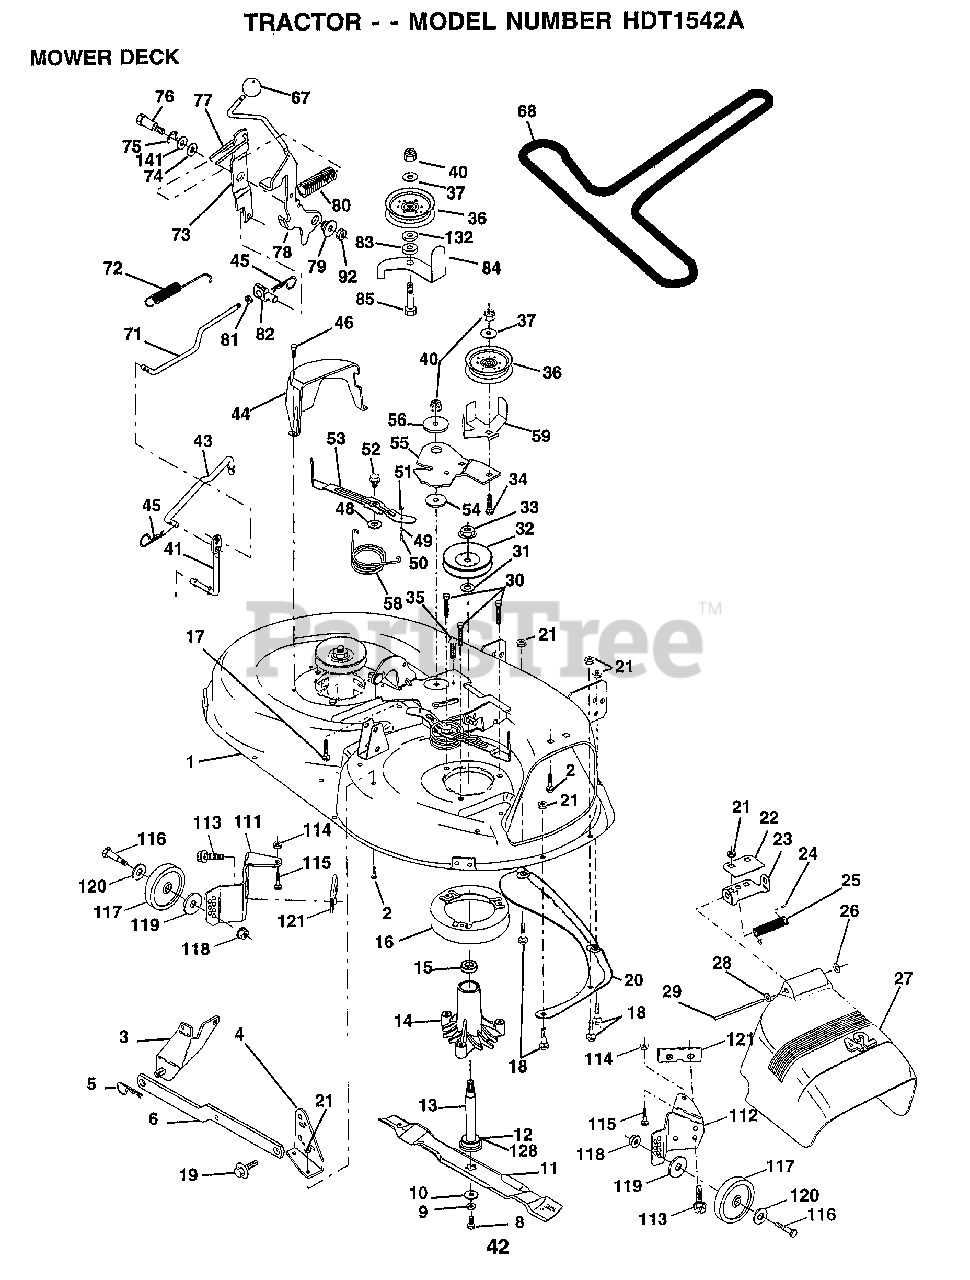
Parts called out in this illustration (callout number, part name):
1	"HOUSING ASSY.42"""
2	BOLT
3	BRKT ASM SWAY BAR
4	BRKT DECK SW BAR
8	BLADE BOLT
10	WASHER.HARD.BLADE
11	"BLADE.42"" HIPERF"
12	BEARING.BALL
14	HSG ASM MANDREL
15	BEARING
16	STRIPPER RND MWR
17	BOLT RDHD 3/8-16
18	BOLT
19	BOLT SHD 5/16-18
20	BAFFLE VORTEX 42
22	STIFFENER BRKT
23	DEFLECTOR BRKT
24	CAP-SLEEVE LT
25	SPRING TORSION
26	NUT PUSH M
27	DEFLECTOR.SHIELD
28	WASHER
29	HINGE ROD
30	"SCREW-THD ROLL,WA"
31	WASHER
32	PULLEY.MANDREL.42
34	BOLT
35	XMAS TREE FASTNER
36	FLAT IDLER PULLEY
37	WASHER
41	PIVOT ROD
43	ROD CLUTCH W/NIBS
44	GUARD MAND LH BLK
45	RETAINER M
46	SCREW.1/4-20X5/8
48	HARD SMALL WASHER
49	ROLLER ASM-CAM
50	SHOULDER BOLT
51	LOCKNUT
52	BOLT.SHLD.5/16-18
53	BRAKE PAD ARM ASM
54	HARDENED WASHER
55	ARM-IDLER
56	SPACER RETAINER
58	SPRING TORSN BRAK
59	GUARD IDLER TUV
67	KNOB.RD.7/16-14
68	BELT.V.T-PATH
71	ROD CLUTCH 38/42
72	RETURN SPRING
73	CLUTCH ARM SECOND
74	WASHER
75	RING
76	SHOULDER BOLT
77	SPRING KEEPER
78	LEVER.ASM.CLUTCH
79	BUSHING
80	SPRING.CLUTCH.MWR
81	NUT
82	TRUNION ADJ
83	WASHER
84	"KEEPER-BELT,FIXED"
85	BOLT
92	NUT
111	BRACKET.GWHL.LH.
112	BRACKET.GWHL.RH.
113	SCREW
116	BOLT M
117	WHEEL.GAGE.BLK.PL
118	LOCKNUT
119	WASHER
120	WASHER
121	BRACKET.EXTRD.GWL
128	WASHER.FELT.
132	WASHER GT
141	WASHER .T
